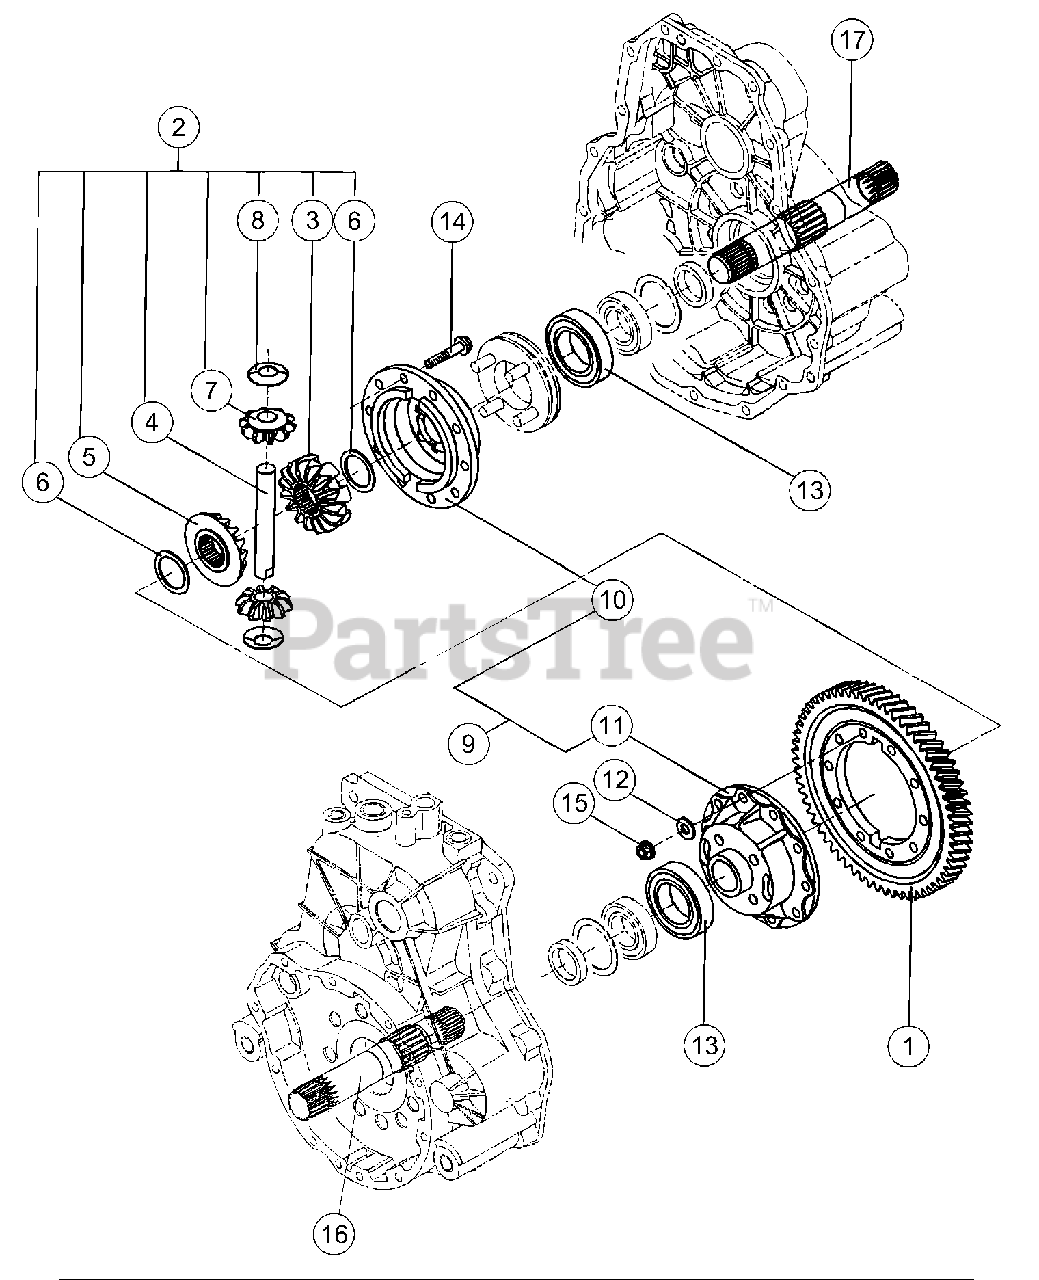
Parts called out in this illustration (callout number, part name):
1	Gear, 63H, Final
2	Differential, Gear Kit
3	Gear (RR, Differential)
4	Shaft, Differential Pinion
5	Differential Side Gear, RH
6	Washer, Differential Gear
7	Pinion, Differential
8	Washer, Differential Pinion
9	Differential, Case Kit
10	Case (R, Differential)
11	Case (L, Differential)
12	Washer, 8
13	Bearing, 6008
14	Bolt, 8 x 40
15	Nut, 8
